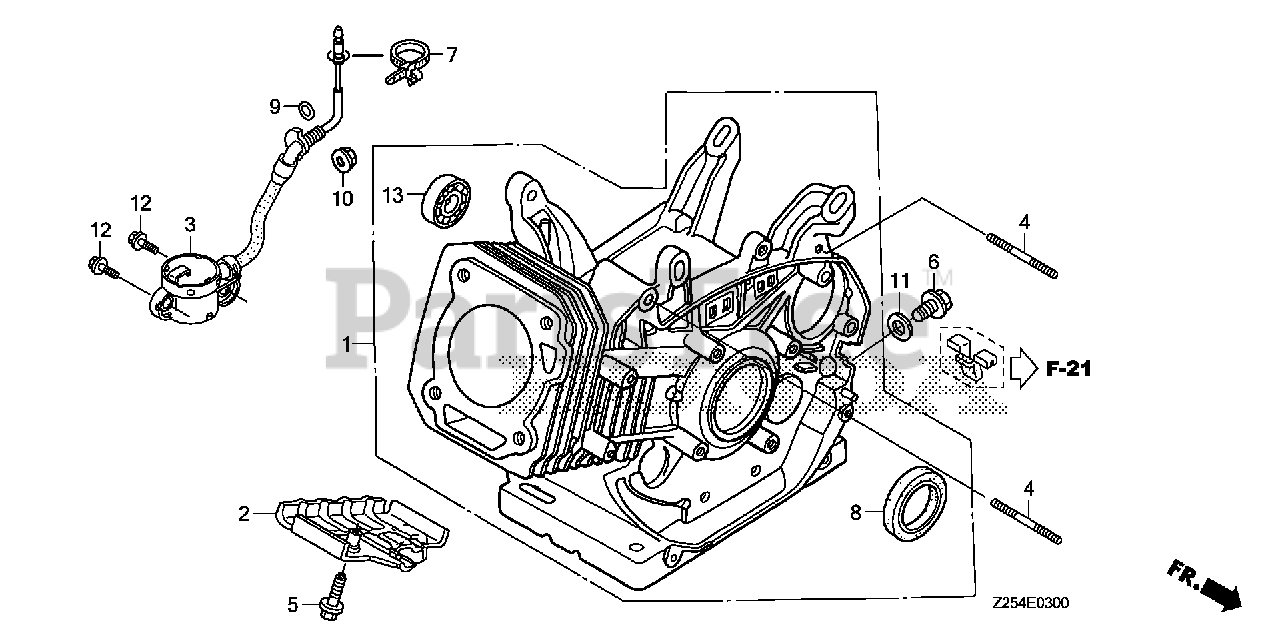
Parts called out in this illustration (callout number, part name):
1	CYLINDER ASSY.
2	SHROUD, ENGINE
3	SWITCH ASSY., OIL LEVEL
4	BOLT, STUD (6X30)
5	BOLT, FLANGE (6X25) Use up to Engine SN 2056819.
6	BOLT, DRAIN PLUG
7	BAND, CABLE
8	OIL SEAL (35X52X8)
9	O-RING (14MM) (ARAI) Use up to Engine SN 2949254.
9	O-RING (14MM) (NOK)
10	NUT, FLANGE (10MM)
11	WASHER, DRAIN PLUG (12MM)
12	BOLT, FLANGE (6X12) Use up to Engine SN 1543277.
13	BEARING, RADIAL BALL (6202)
